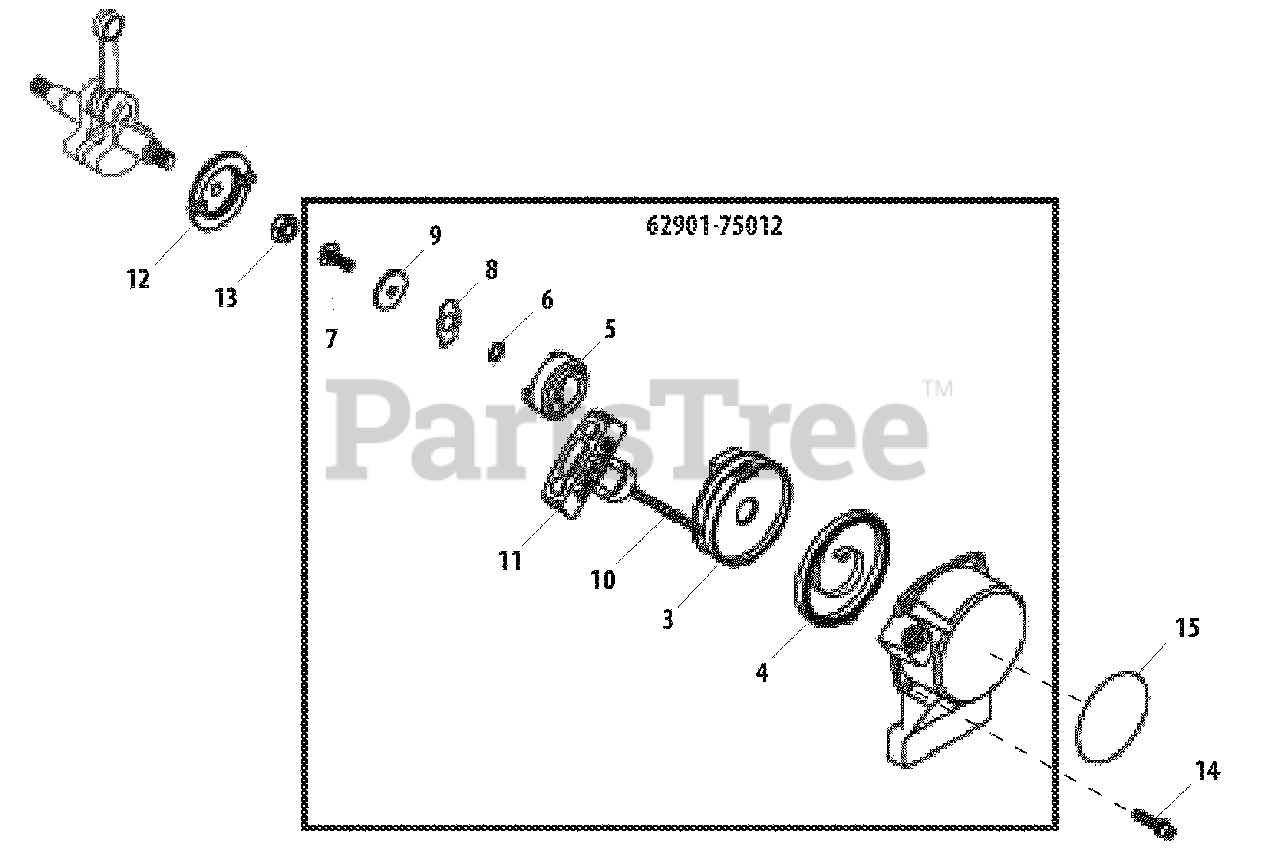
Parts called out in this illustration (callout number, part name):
3	REEL, ROPE
4	SPRING, RECOIL
5	PAWL, STARTER
6	WASHER, WAVE
7	SCREW 5 MM
8	RETAINER
9	WASHER 5 MM
10	ROPE, STARTER
11	GRIP, STARTER
12	PULLEY, STARTER
13	NUT M8×1
14	BOLT M4×16
15	LABEL, RECOIL C4
62901-75012	STARTER ASSY, RECOIL
